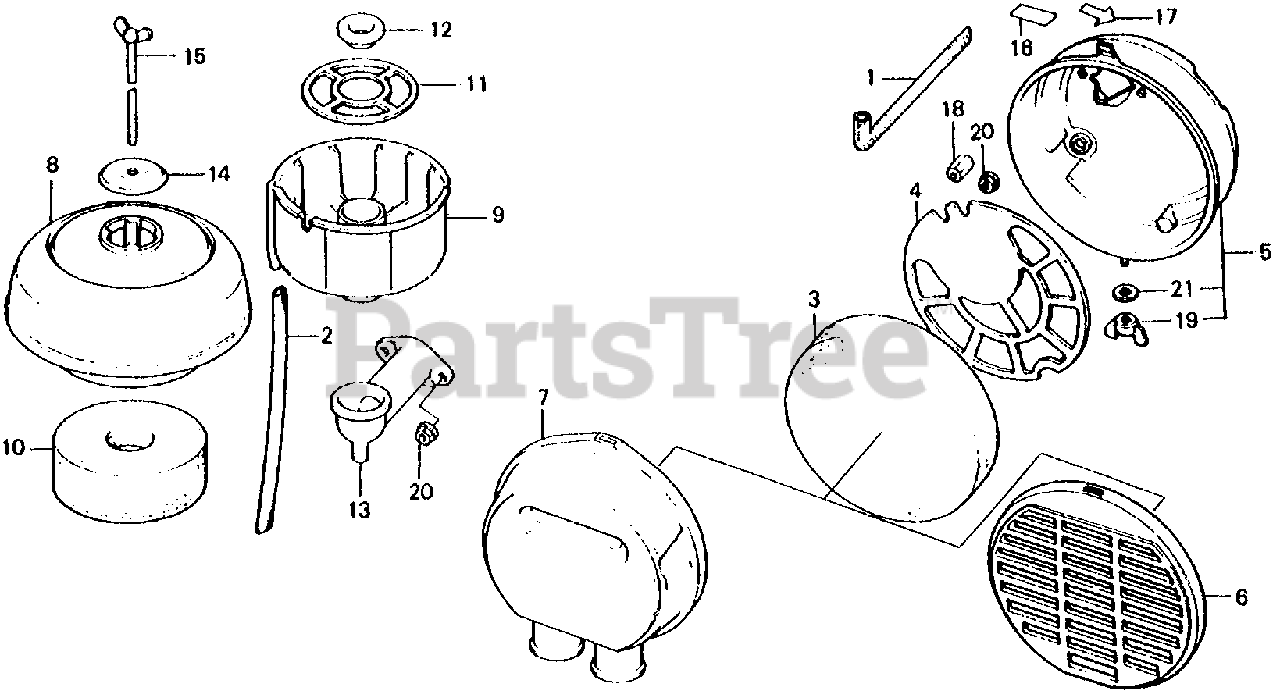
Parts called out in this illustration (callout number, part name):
1	TUBE, BREATHER
3	ELEMENT, AIR CLEANER
4	GRID, AIR CLEANER
5	HOUSING, AIR CLEANER
6	COVER, AIR CLEANER
7	COVER, AIR CLEANER
16	MARK, CHOKE
17	MARK, CHOKE
18	NUT (6X15)
19	WINGNUT, TOOL BOX SETTING
20	NUT, FLANGE (6MM)
21	WASHER, PLAIN (6MM)
